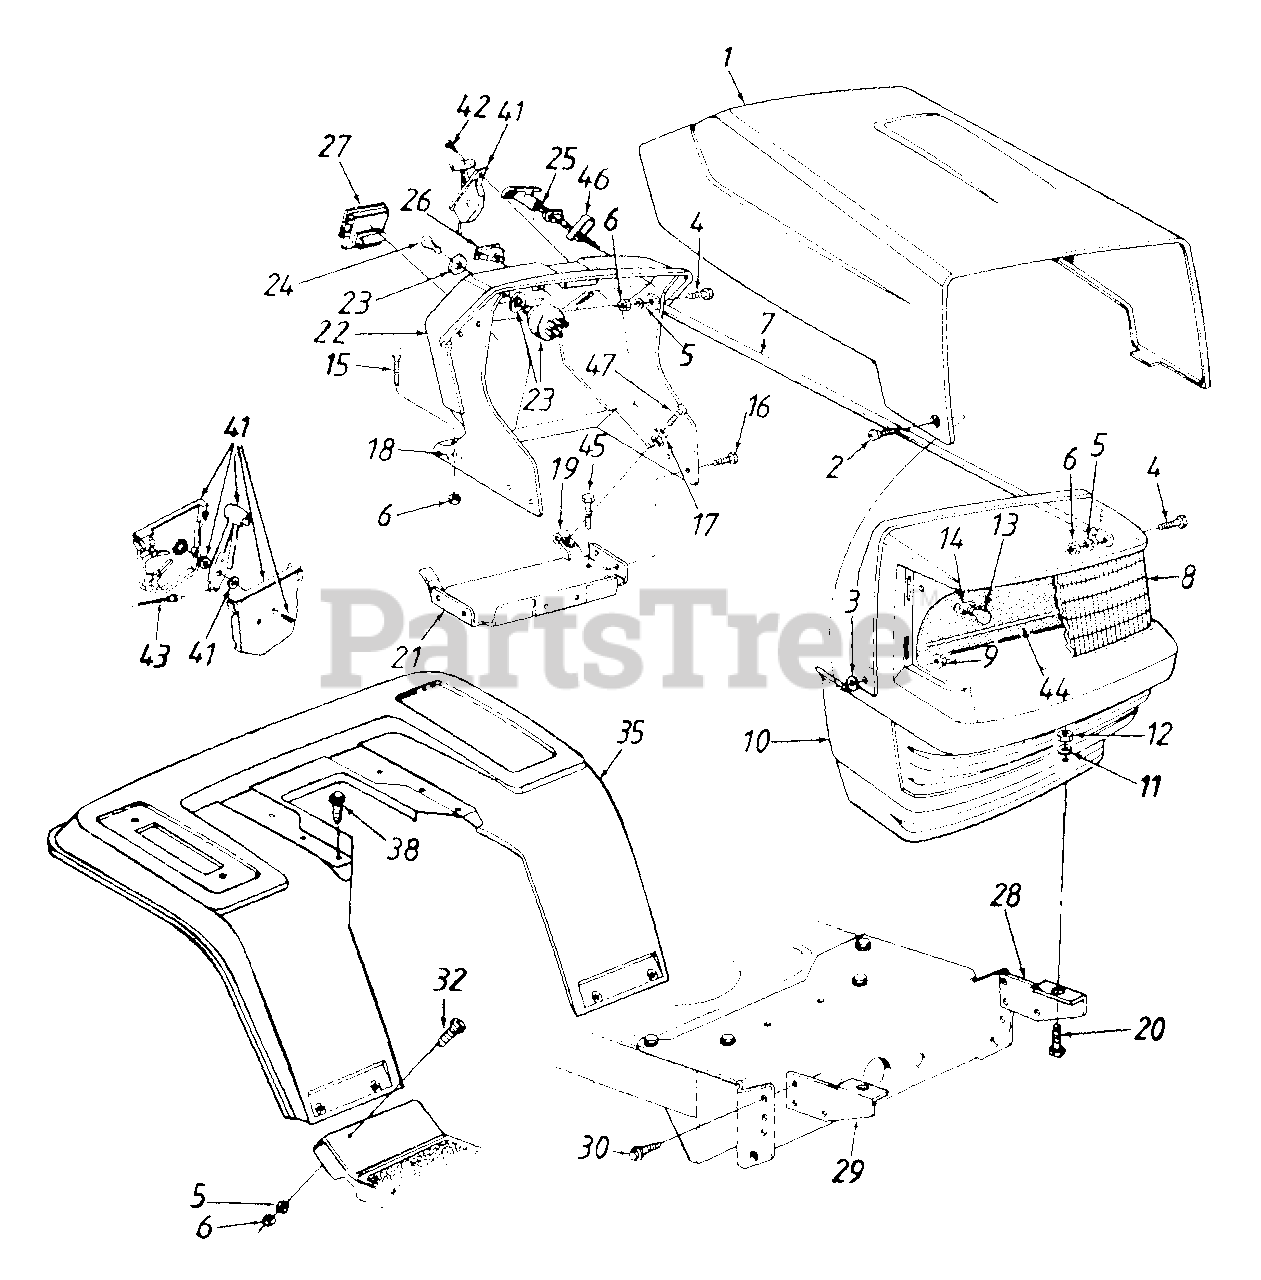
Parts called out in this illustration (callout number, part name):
3	Fl-Wash. .28" I.D. x .75" O.D.
4	Hex Bolt 1/4-20 x .62" Lg."
5	L-Wash. 1/4" I.D.
6	Hex Nut 1/4-20 Thd.
8	Headlight Lens
9	Flange L-Nut 1/4-28 Thd.
10	Grille
11	Fl-Wash. .344" I.D. x 1" O.D.
12	Hex Nut 5/16-18 Thd."
13	Lamp
14	Socket
15	Carriage Bolt 1/4-20 x .75" Lg.
16	Hex Wash. Hd. TT-Tap Scr. 1/4-20 x .5" Lg.
17	Fl-Wash. .281" I.D. x .73" O.D.
18	Bolt Retainer 1/4" I.D.
19	Speed Nut 1/4-20 Thd.
20	Hex Bolt 5/16-18 x .75" Lg.
23	Ignition Switch
24	Ignition Key
25	Choke Control
26	Light Switch
27	Ammeter
28	Grille Mtg. Brkt.- L.H.
32	Truss Mach. Scr. 1/4-20 x .5" Lg.
41	Throttle Box Ass'y.
42	Truss Mach. AB-Tap Scr. #10 x .5" Lg.
43	Throttle Control Wire
44	Grille Reflector Label
45	Hex Wash. Hd. B-Tap Scr. 5/16-18 x .5" Lg.
46	Choke Retainer
47	Hex TT-Tap Scr. 1/4-20 x .75" Lg.
